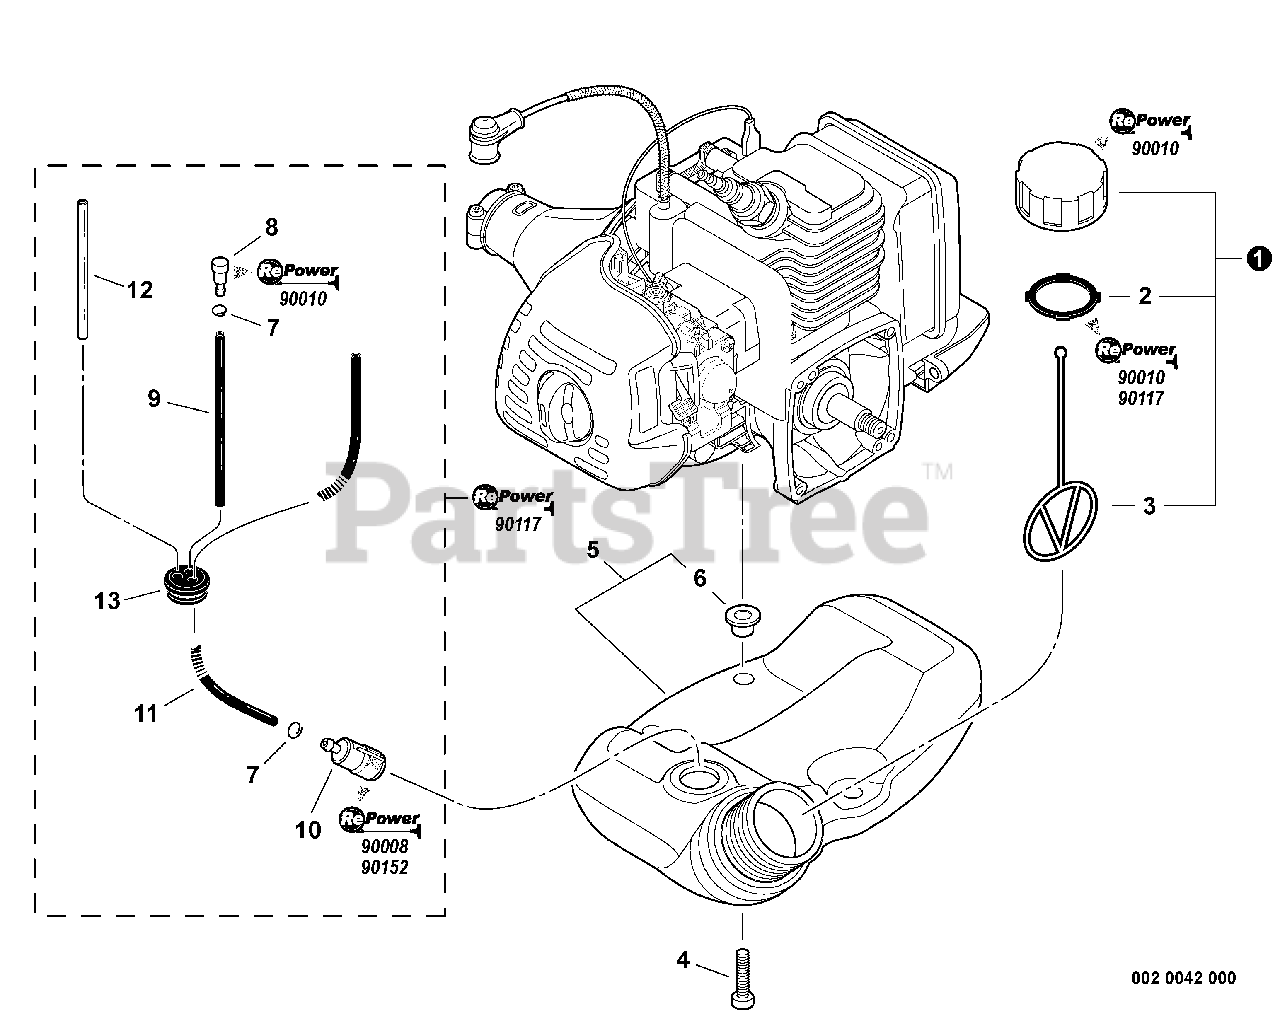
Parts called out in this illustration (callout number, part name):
1	CAP ASSY, FUEL
2	GASKET, FUEL CAP
3	CONNECTOR, CAP L= 123
4	BOLT, TORX 5×20
5	TANK ASSY, FUEL
6	COLLAR 5
7	CLIP 6 MM
8	VENT ASSY
9	PIPE, FUEL 3×5×90 BLACK
10	FILTER, FUEL
11	PIPE, FUEL 3×5×210 BLACK
12	PIPE, FUEL 3×6×80 CLEAR
13	GROMMET, FUEL
14	FUEL SYSTEM KIT
15	TUNE-UP KIT - REPOWER
16	FILTER KIT - REPOWER
17	CAP/VENT KIT - REPOWER
18	BULK PIPE - 3×5 MM BLACK (4 PIECES×2 M)
19	BULK PIPE - 3×6 MM CLEAR (4 PIECES×2 M)
